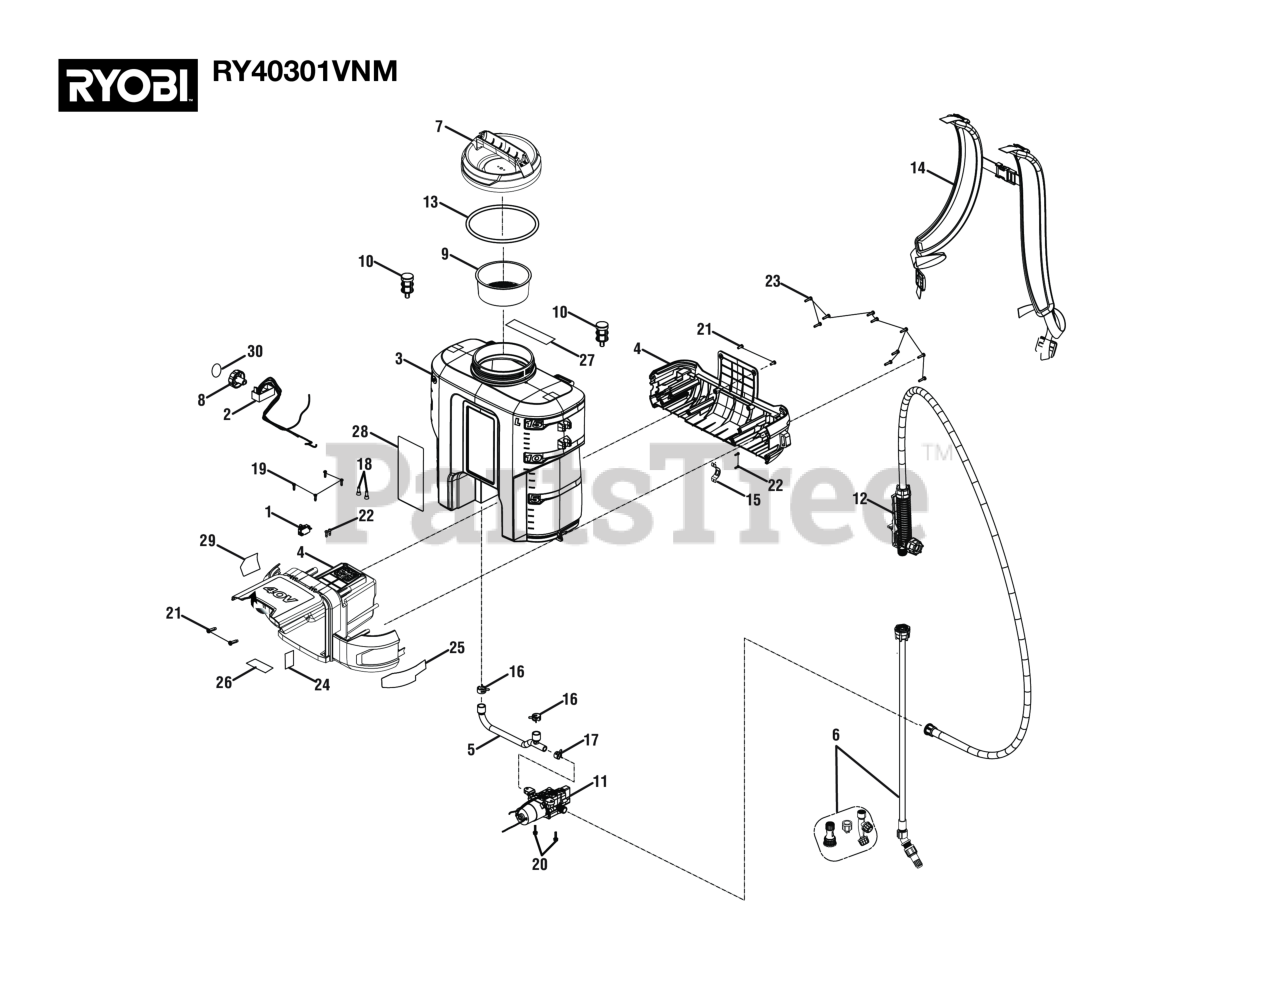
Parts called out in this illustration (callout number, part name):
1	Micro Switch
2	Flow Rate Control
3	Tank Assembly (Inc. Key Nos. 27-28)
4	Housing Assembly (Inc. Key Nos. 24-26 & 29)
5	Pickup Tube
6	Wand and Nozzle Assembly
7	Tank Lid Assembly (Inc. Key No. 11)
8	Adjustable Switch Knob Assembly (Inc. Key No. 19)
9	Inlet Filter
10	Filter Assembly
11	Motor and Pump Assembly
12	Handle and Hose Assembly
13	Rubber Gasket
16	Hose Clamp on Tank
17	Hose Clamp on Pump
18	Wire Connector (Closed End)
19	Screw (M4 x 14 mm, T15 Torx Pan Hd.))
20	Screw w/Washer (M4 x 19 mm, T20 Torx Pan Hd. S.T.)
21	Screw (M4 x 12 mm, T20 Torx Hd.)
22	Screw (M3 x 10 mm, T10 Torx Hd.)
23	Screw (M4 x 18 mm, T20 Torx Pan Hd. S.T.)
24	Data Label
25	Warnings Label (FR/SP)
26	QR Code Label
27	Icon Warning Label
28	Logo Label
29	4 Gal. Callout Label
30	On\Off Label
